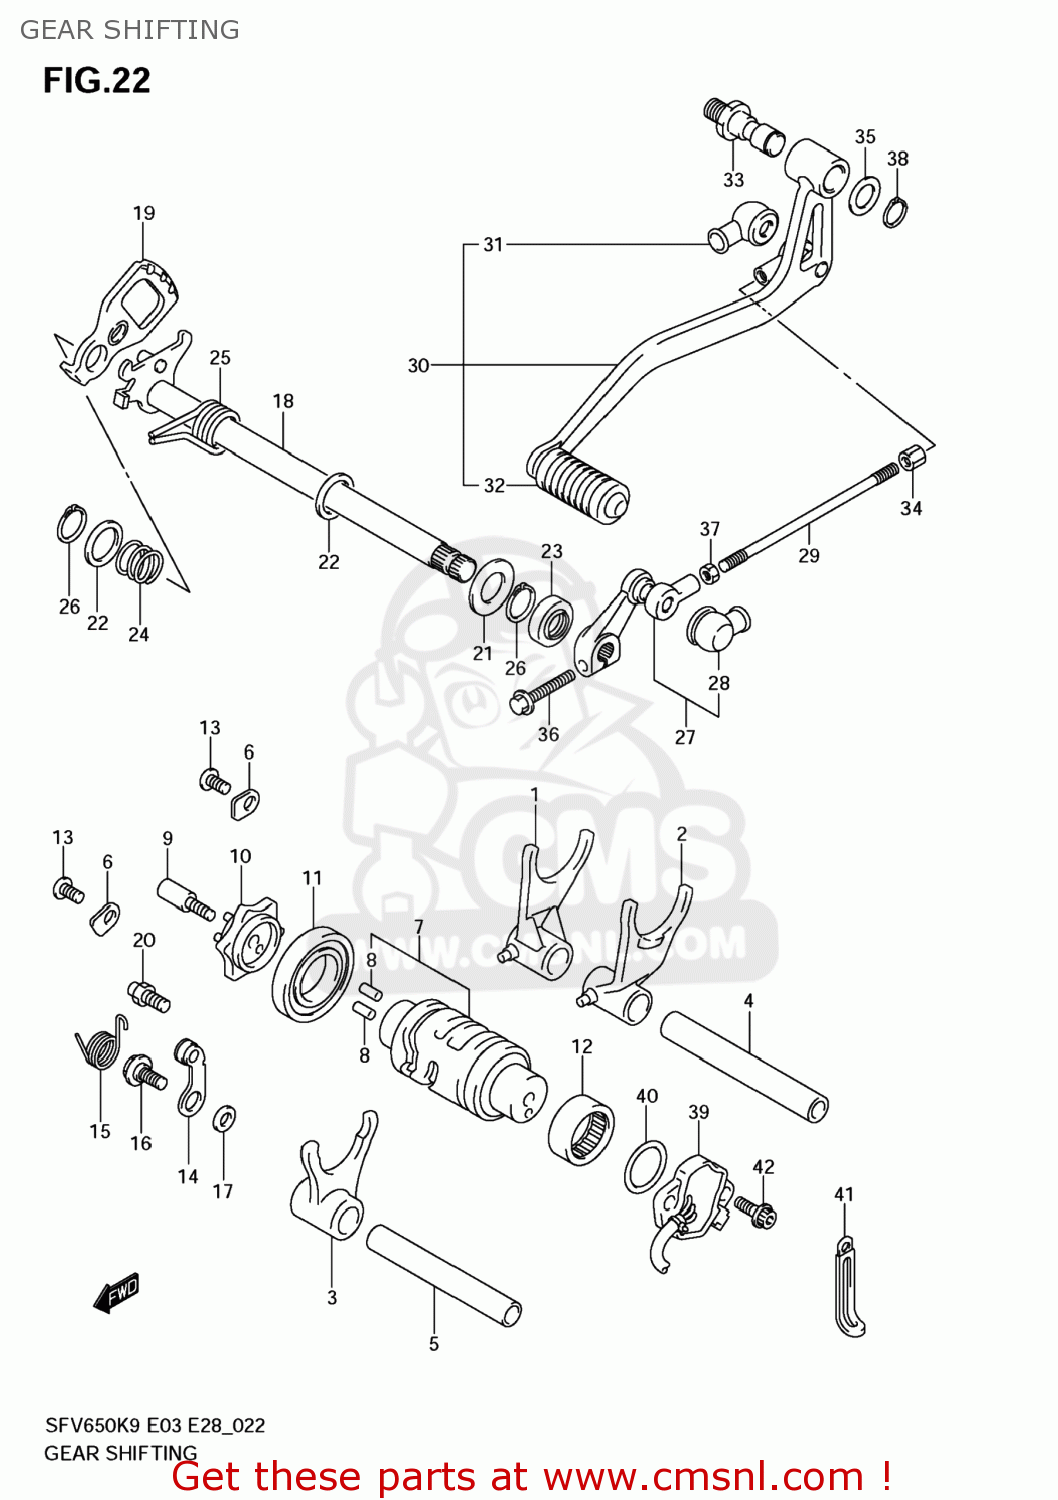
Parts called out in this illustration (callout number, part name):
1	FORK,GEAR SHIFT NO.1
2	FORK,GEAR SHIFT NO.2
3	FORK,GEAR SHIFT NO.3
4	SHAFT,GEAR SHIFT FORK
5	SHAFT,GEAR SHIFT FORK NO.1
6	RETAINER
7	CAM,GEAR SHIFT
8	PIN
9	BOLT,GEAR SHIFT CAM PLATE
10	PLATE,GEAR SHIFT CAM
11	BEARING(25X47X8)
12	BEARING(25X32X12)
13	SCREW
14	STOPPER,SHIFT CAM
15	SPRING,SHIFT
16	BOLT(6X14.3)
17	WASHER
18	SHAFT,GEAR SHIFT
19	PLATE,GEAR SHIFT CAM DRIVE
20	STOPPER,GEAR SHIFT ARM
21	WASHER(14X29X0.8)
22	SHIM(14X22X1)
23	SEAL,OIL(14X22X6)
24	SPRING
25	SPRING
26	CIRCLIP
27	ARM,GEAR SHIFT LINK
28	COVER,DUST
29	ROD,GEAR SHIFT LINK
30	LEVER ASSY,GEAR SHIFT
31	COVER,DUST
32	RUBBER,GEAR SHIFT PEDAL
33	SHAFT,GEAR SHIFT LEVER
34	NUT
35	WASHER(12.5X20X1)
36	BOLT
37	NUT
38	CIRCLIP
39	SENSOR ASSY,GE
40	O RING(D:2.4,ID:26.2)
41	CLAMP(L:80)
42	BOLT
